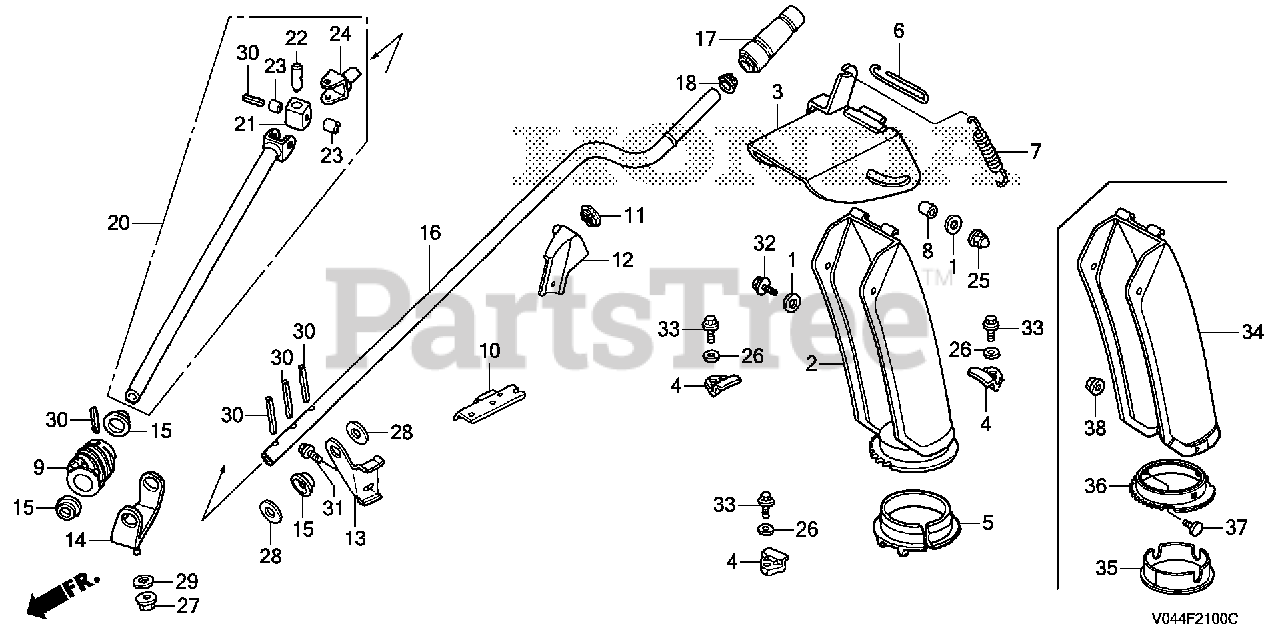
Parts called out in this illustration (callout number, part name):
1	WASHER, ACCELERATOR PEDAL
2	CHUTE
3	GUIDE, CHUTE (COO)
4	PLATE, CHUTE SETTING
5	BUSH, CHUTE
6	PIN, CHUTE GUIDE
7	SPRING, CHUTE
8	COLLAR, CHUTE GUIDE
9	GEAR, CHUTE DRIVE
10	HOLDER, HANDLE BRACKET
11	BUSH, CHUTE HANDLE
12	BRACKET A, CHUTE HANDLE
13	BRACKET B, CHUTE HANDLE
14	STAY, DRIVE GEAR
15	BUSH, DRIVE GEAR
16	HANDLE, CHUTE (UPPER)
17	GRIP, CHUTE HANDLE
18	BUSH A, CHUTE HANDLE
20	HANDLE, CHUTE (LOWER)
21	PIECE, JOINT
22	PIN A, JOINT
23	PIN B, JOINT
25	NUT, CAP (6MM)
26	WASHER, CHUTE SETTING
27	NUT, FLANGE (8MM)
28	WASHER, PLAIN (16MM)
29	WASHER, PLAIN (8MM)
30	PIN, SPRING (4X28)
31	BOLT, FLANGE (6X12) Use up to Engine SN 1543277.
32	BOLT, FLANGE (6X14)
33	BOLT, FLANGE (8X12)
34	CHUTE
35	BUSH, CHUTE
36	GEAR, CHUTE
37	BOLT, SPECIAL (9X15)
38	NUT, FLANGE (8MM)
